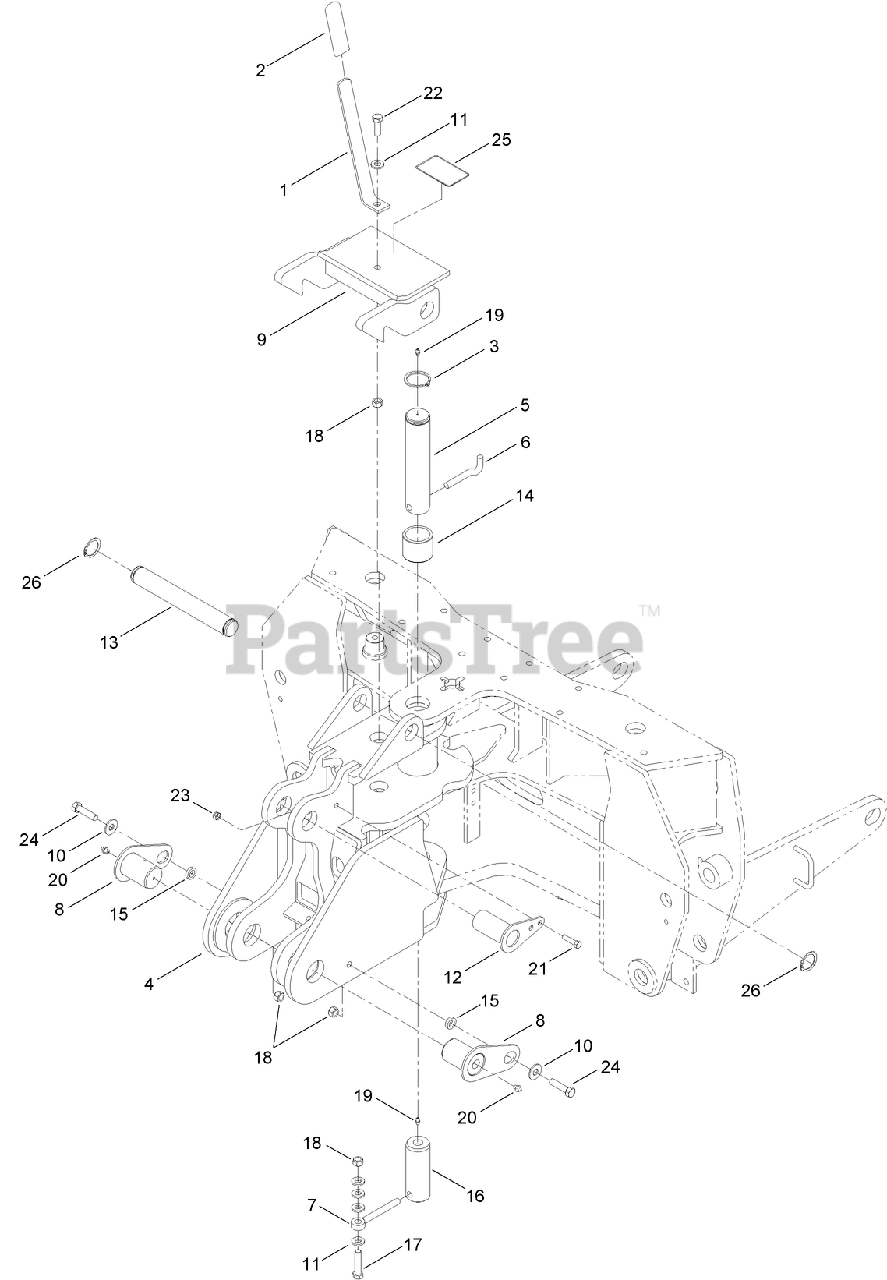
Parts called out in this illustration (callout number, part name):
2	GRIP-HANDLE
3	RING-RETAINING, EXTERNAL
4	TOWER-SWING
5	PIN (TOP SWING PIVOT)
6	PIN-RETAINER
7	PIN-RETAINER
8	PIN (BOOM PIVOT)
9	LATCH-LOCK, BOOM
10	WASHER-FLAT
11	WASHER-FLAT
12	PIN-BOOM (CYLINDER)
13	PIN (LATCH TO SWING TOWER)
14	BUSHING
15	SPACER-PIN
16	PIN (LOWER SWING PIVOT)
17	SCREW-HH
18	NUT-HEX
19	FITTING-GREASE
20	FITTING-GREASE
21	SCREW-HH
22	SCREW-HH
23	NUT-HEX
24	SCREW-HH
25	DECAL-OPERATOR PRESENCE
